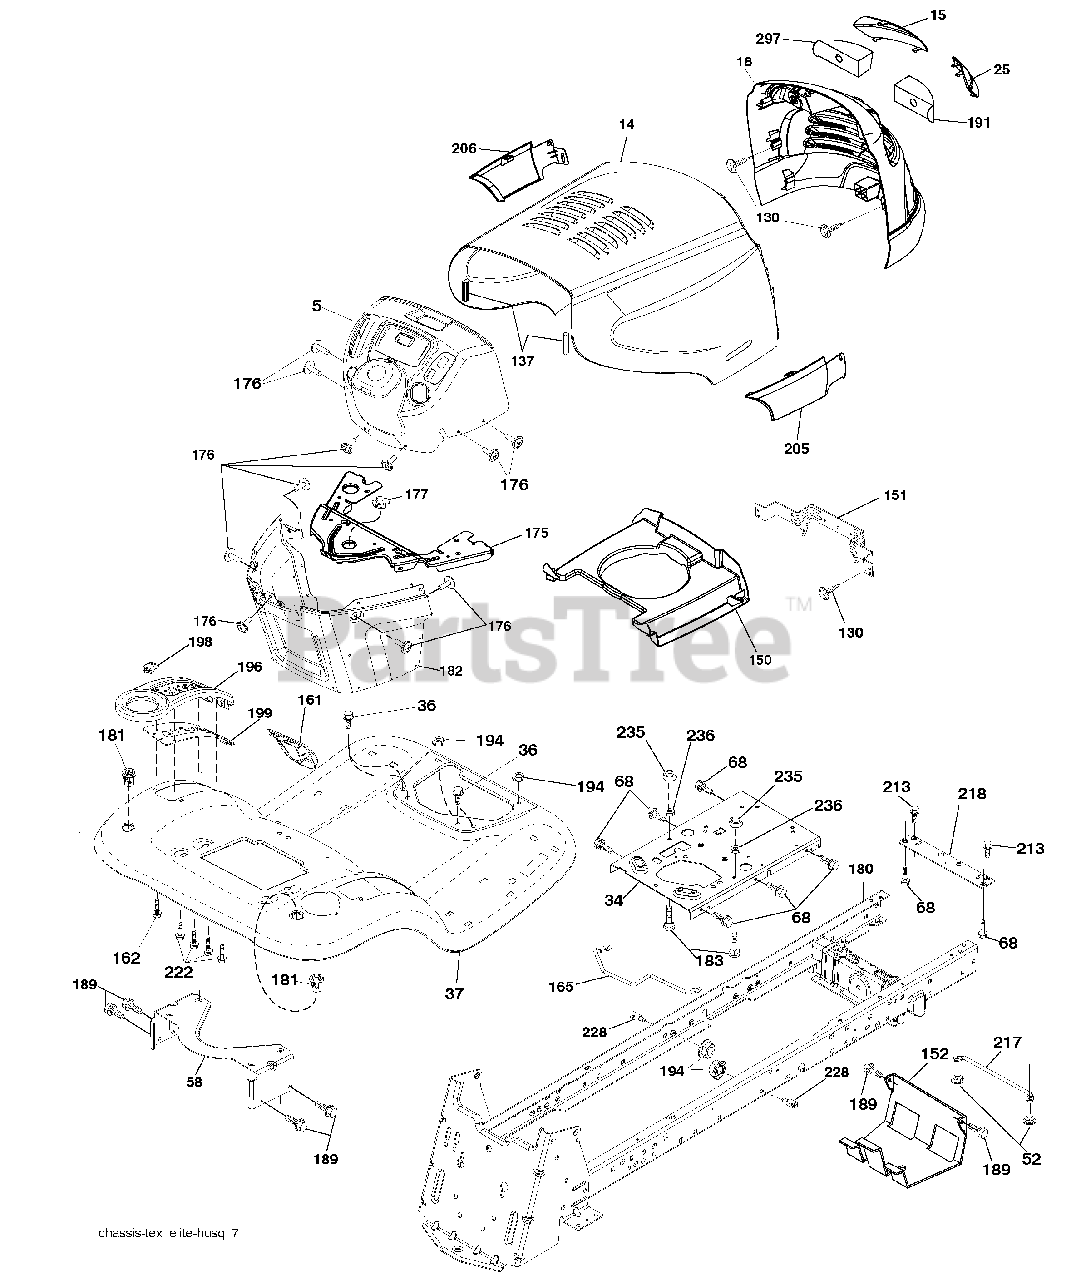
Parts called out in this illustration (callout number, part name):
5	Dash
14	Hood
15	Lens Grille LH
18	Grille
25	Lens Grille RH
34	Plate Engine
36	Screw 5/16-18 x 3/4
52	Nut Crown Lock 5/16-18
58	Fender Support Bracket
68	Screw THDROL 5/16-18 x 1/2
130	Screw #10 x 0.750 BOS Thread
137	Bumper Hood
150	Duct Heat Hood
151	Bracket Pivot
152	Shield Browning/Debris
161	Window Fuel
162	Screw Hex Wsh Hi-Lo 1/4 x 1/2 unc
165	Support Tank Rear
175	Crossmember
176	Screw 10-24 x 5/8 Wshd Qdrx
177	Bushing Steering
180	Chassis
181	Bushing Mtg. Fender Crgo.
182	Dash Lower
183	Bolt Full Thd. 5/16-18 x 1-1/4
189	Screw 5/16-18 x 3/4
191	Insert Lens Reflective RH
194	Nut Lock Hex Flange 5/16-18
196	Console Asm. Deck Lift
198	Indicator Deck Lift
199	Plate Deck Lift
213	Bolt Hex HD 5/16-18 unc x 3/4
217	Rod Pivot
218	X-Piece Hood
222	Screw Thd. Roll 1/4-20 x 5/8
228	Stud Fastener
235	Spacer Fender
236	Nut Center Lock 5/16-18 unc
297	Insert Lens Reflective LH
297	Plug Cruise Hook Phone
